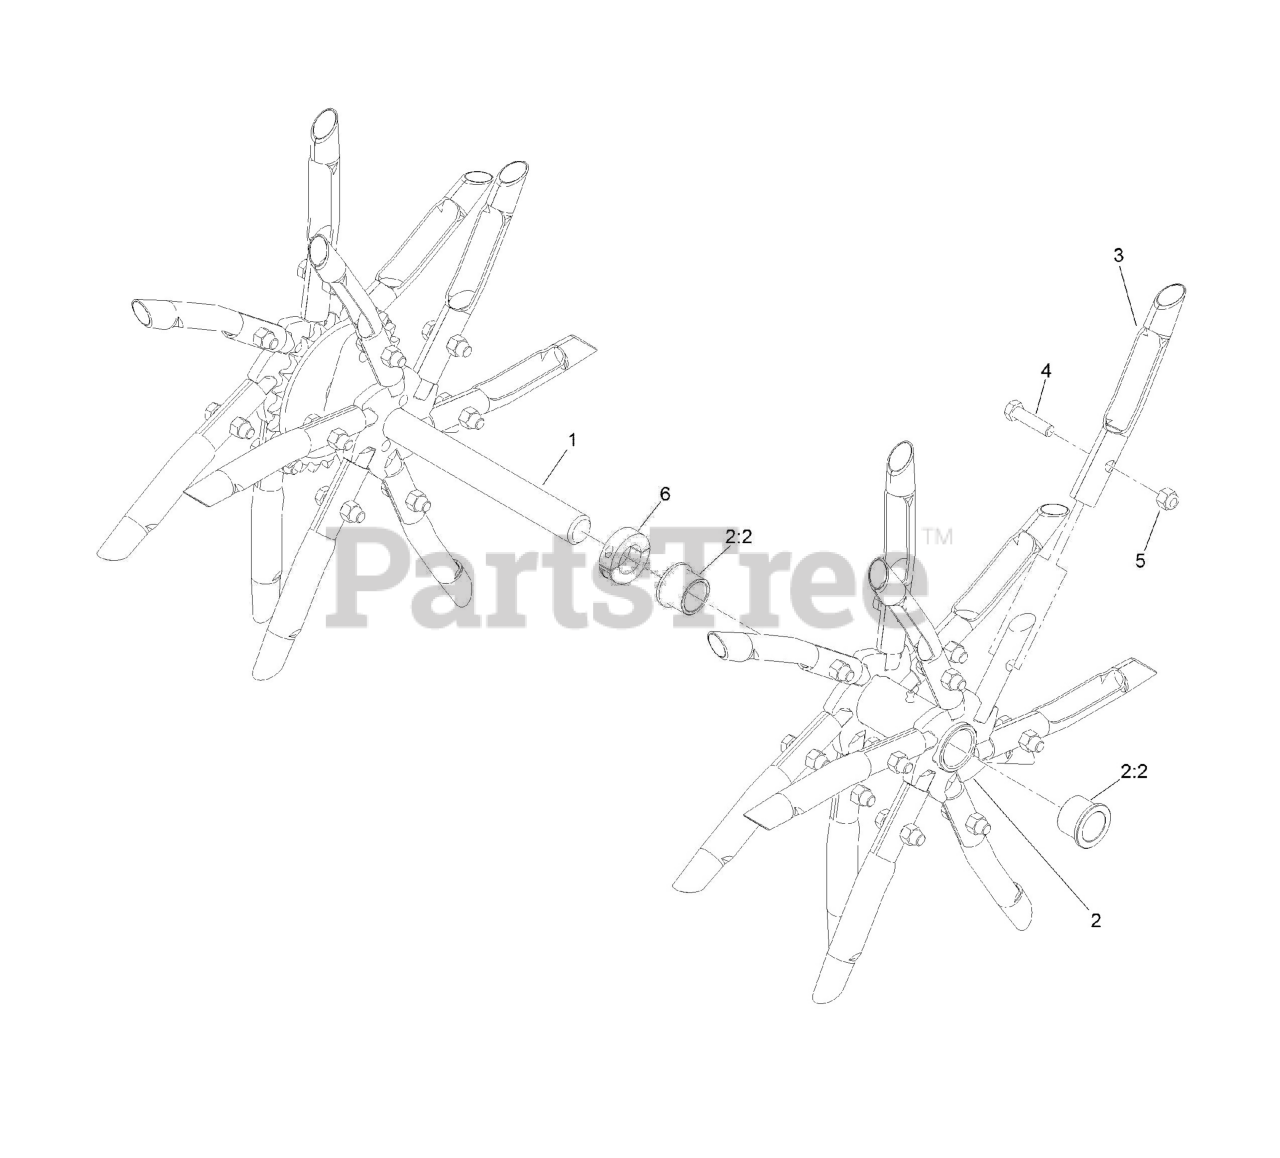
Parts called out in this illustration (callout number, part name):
1	TINE SHAFT-RH
2	ASM-FLOAT TINE SHAFT
2:2	BUSHING-FLANGE
3	TINE-CORING (3/4 INCH)
4	SCREW-HH
5	NUT-LOCK, NI
6	COLLAR-LOCKING
